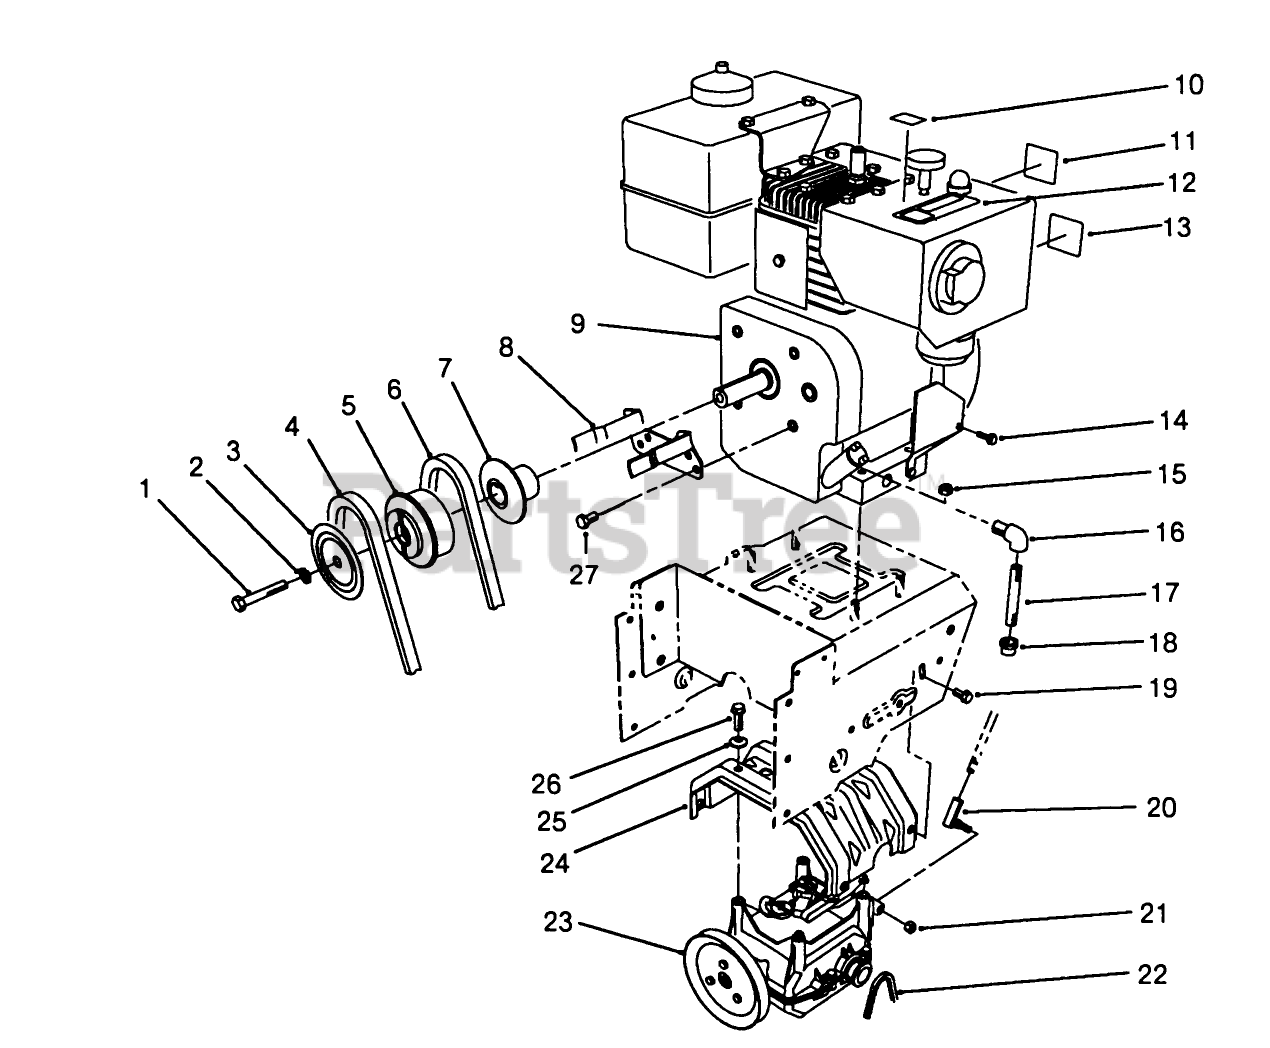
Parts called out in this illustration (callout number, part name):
1	SCREW-HH
2	WASHER-LOCK
3	SHEAVE-HALF, IMPELLER
4	V-BELT
5	PULLEY-ENGINE, CENTER
6	V-BELT, TRACTION
10	DECAL - CHOKE
13	DECAL - THROTTLE, INT'L
15	NUT-HF
16	ELBOW
17	NIPPLE-PIPE
18	CAP-PIPE
19	SCREW-HHF
21	NUT-LOCK
25	WASHER-SPRING
27	SCREW-THD ROLL, HWH
